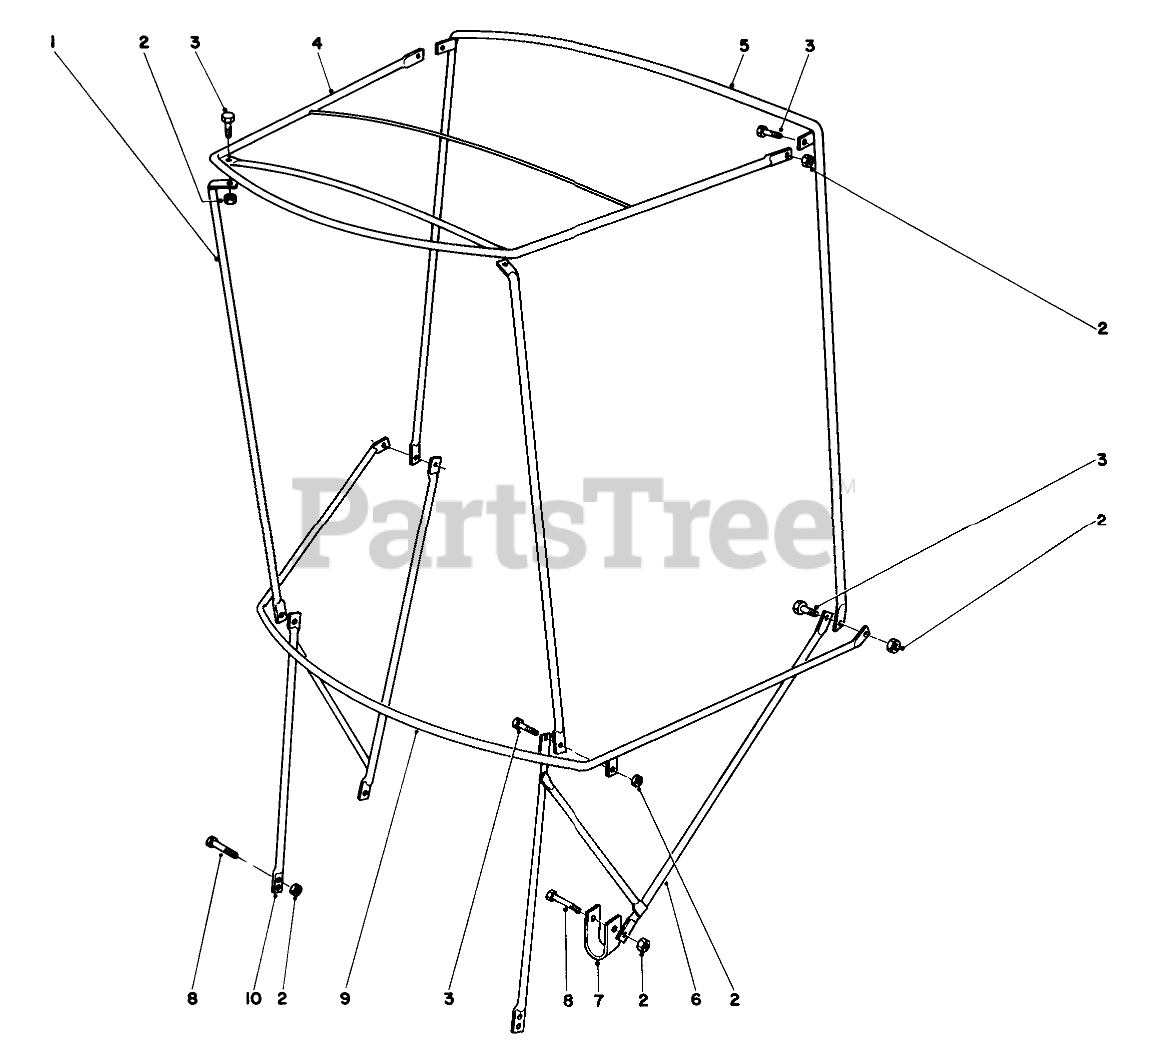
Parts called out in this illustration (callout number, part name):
2	NUT-HEX, SIDE DEFORM
3	Bolt
4	FRAME-TOP
5	BOW-VERTICAL, REAR
6	Attaching Bracket
7	U CLAMP
8	SCREW-HH
9	BOW-CURVED
10	Attaching Bracket R.H.
